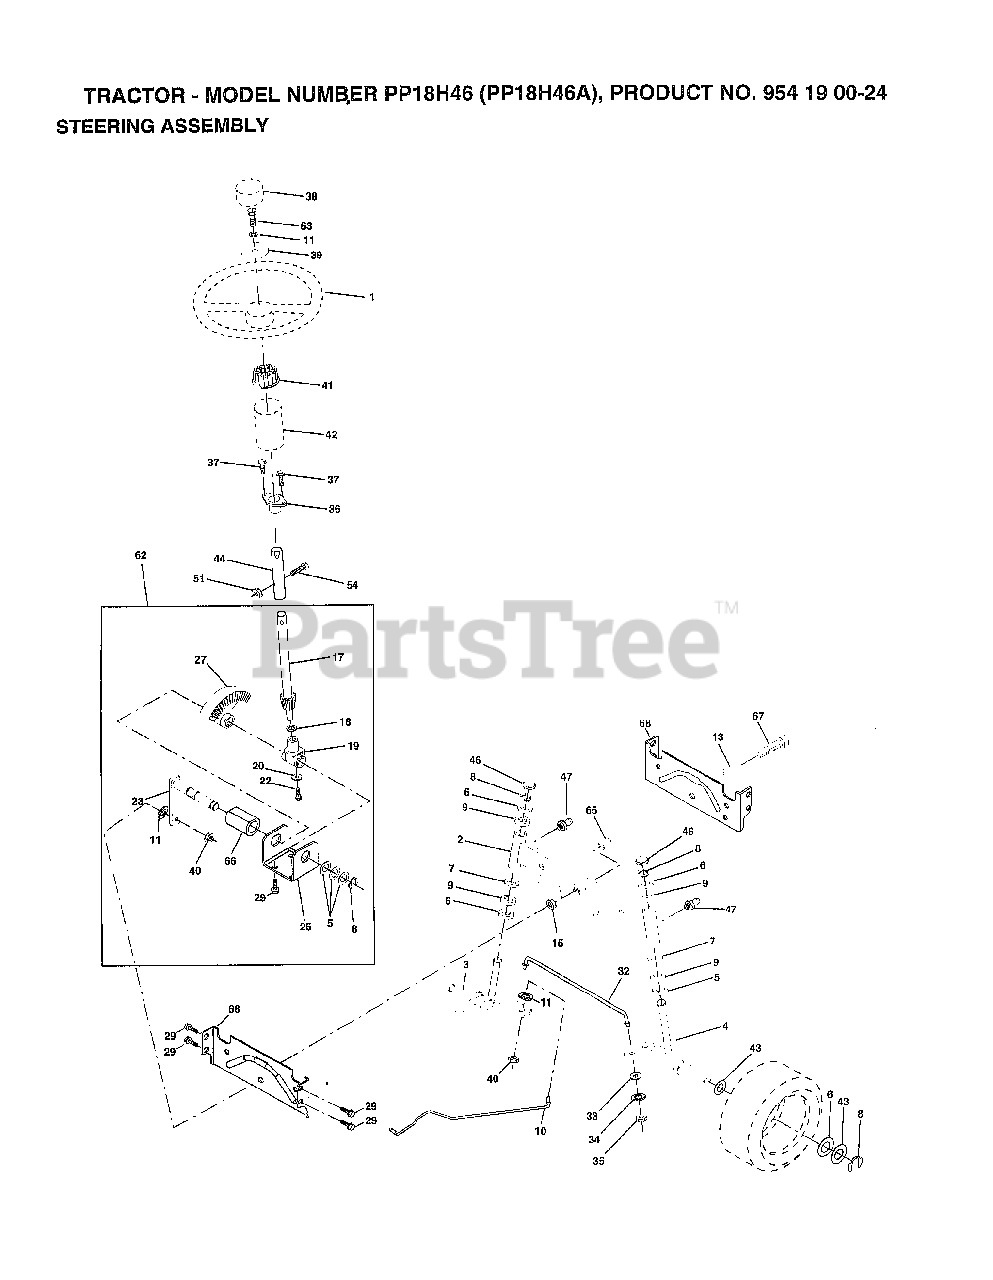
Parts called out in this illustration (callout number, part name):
2	AXLE ASM
3	SPINDLE.ASM.LH
4	"SPINDLE ASM,RH"
6	WASHER
7	WASHER
8	RING
9	COL. SRTG. BEAR.
10	DRAGLINK-STAMPED
11	LOCKWASHER
13	BEARING AXLE
15	"NUT-LOC,FLANGE LT"
17	SHAFT ASM STEERIN
18	THRUST WASHER
19	SUPPORT SHAFT
20	WASHER SHIM 1/4 X 5/8 X 062
22	SCREW HEX SOC1/4-
25	BRKT-STEERING
27	GEAR SECTOR
29	SCREW
32	ROD.TIE.19.75
33	WASHER M
34	LOCKWASHER
35	NUT.LOCK.5/16-24
36	BUSHING.STEERING
37	"SCREW-TT,10-32 FL"
38	"INSERT,STR WHEEL"
39	WASHER T
40	GRIPCO NUT
41	ADAPTER LT
42	BOOT.STEER.PL
43	WASHER
44	EXT SHAFT STEERIN
46	CAP
47	ZERK M
51	NUT
54	BOLT
62	KIT STEERING ASM
63	BOLT
65	SPACER AXLE
66	"BEARING-ARM,PITMA"
67	BOLT
68	BRACE AXLE
